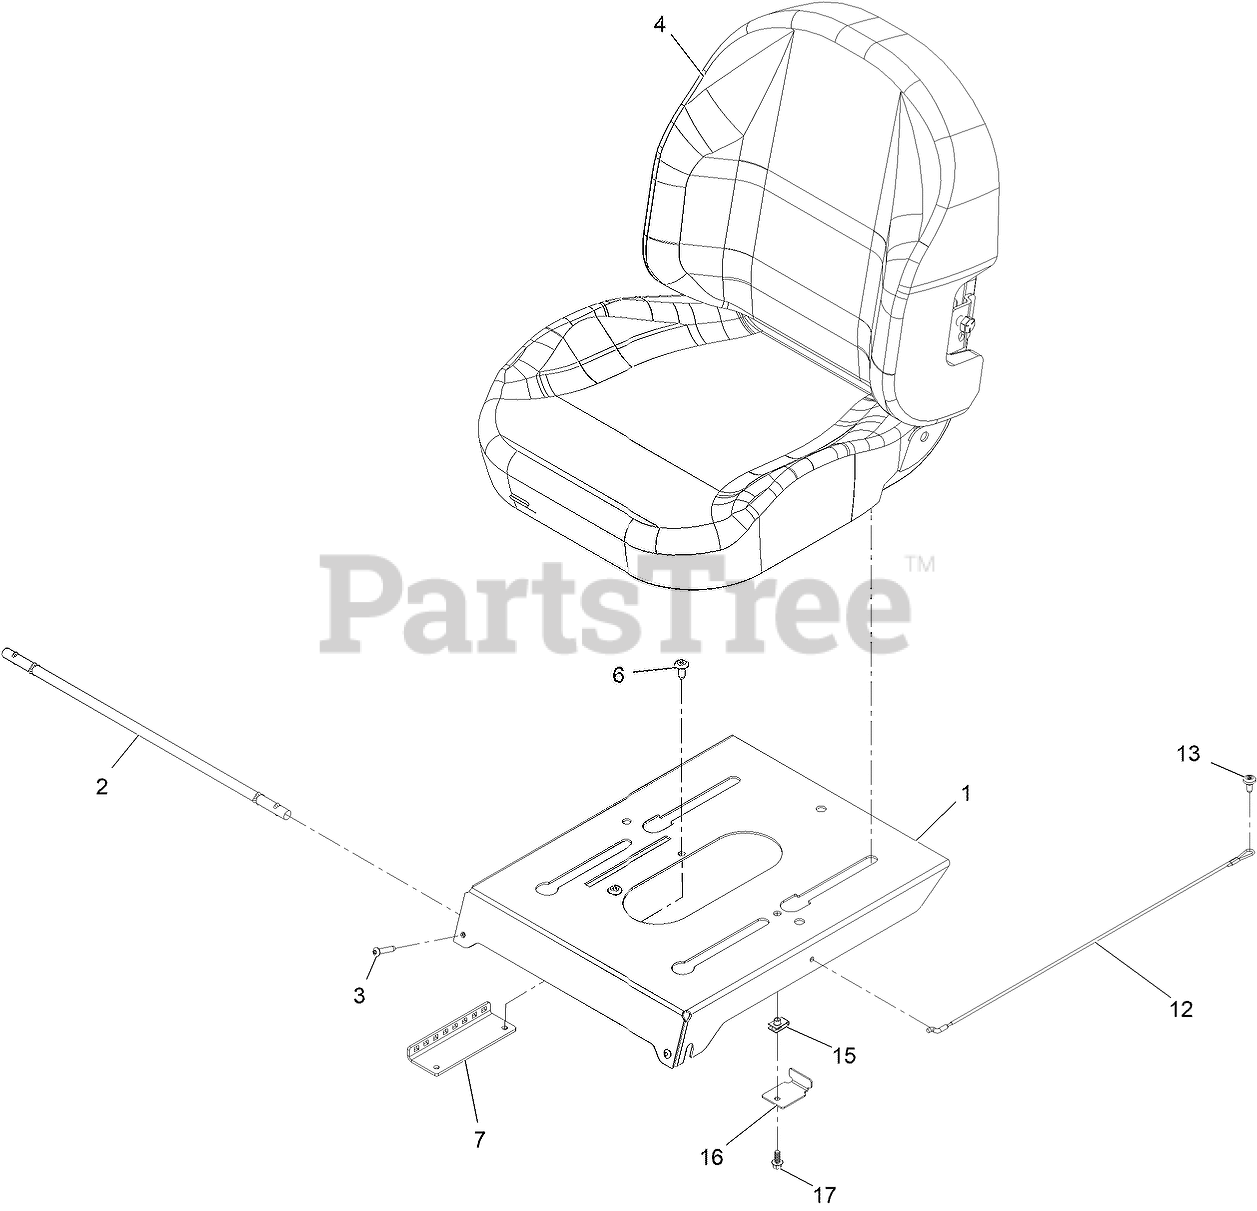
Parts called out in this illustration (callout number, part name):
2	ROD-PIVOT
3	SCREW-TTH, THREAD ROLLING
4	ASM-Seat Exmark
7	BRACKET-LATCH, SEAT
12	CABLE-LANYARD
13	SCREW-SHOULDER
16	Bracket-Stop, Seat
17	SCREW-HHF
